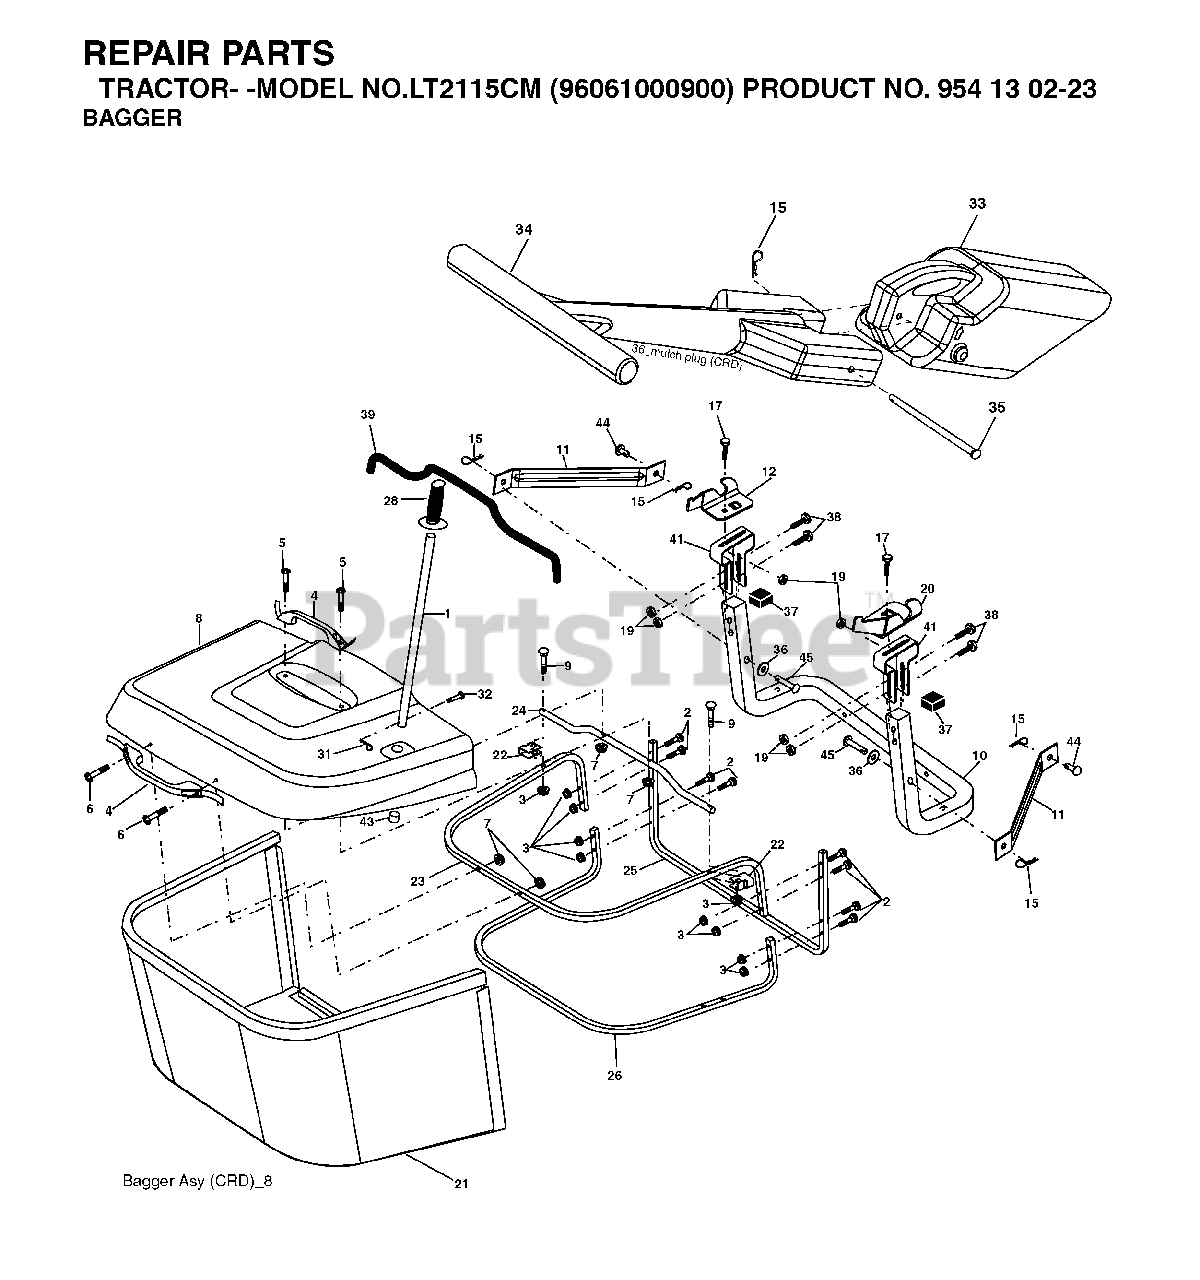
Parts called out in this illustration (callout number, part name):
1	TUBE HANDLE
3	NUT T
5	SCREW.PAN.HEAD
11	BRACKET
15	RETAINER-SPRNG RB
17	BOLT
19	NUT LOCK HEX FLANGE 5/16-18
20	BRKT.PIVOT.RH.CRD
21	GRASS BAG
22	BRACKET
23	TUBE
24	TUBE
26	TUBE
28	GRIP.HANDLE.BLACK
31	RETAINER CLIP
32	RIVET,DRILLED
33	PLUG
35	PIN
38	BOLT.5/16-18X2.5
41	BRKT, BAGGER
43	PLUG, TUBING END
